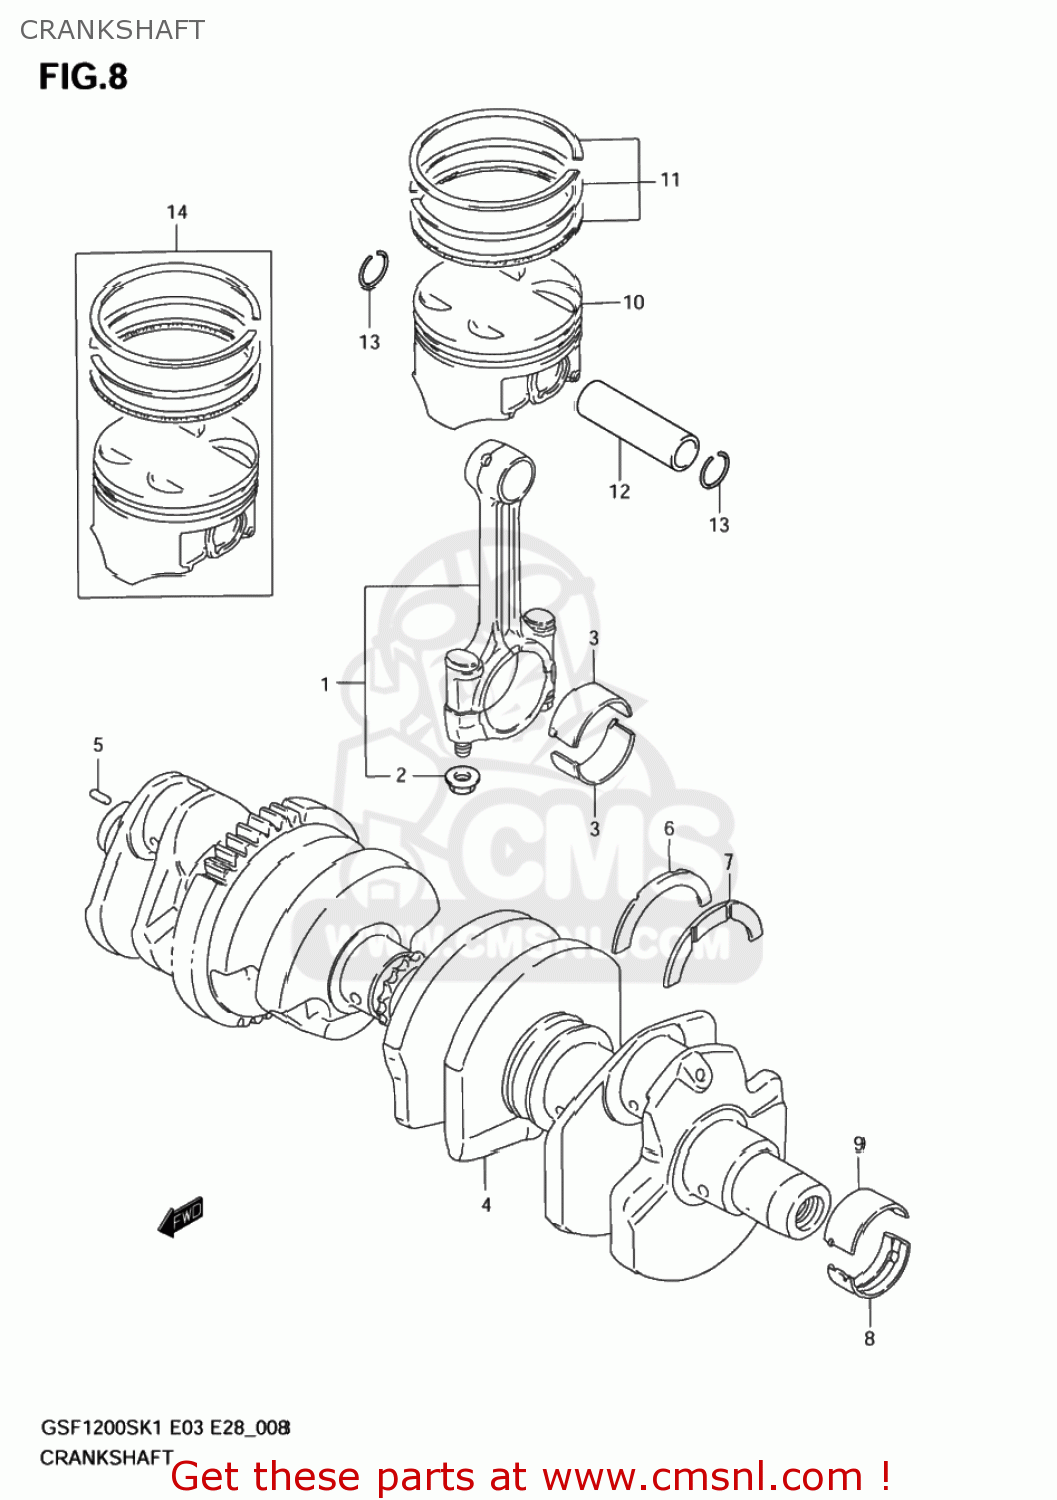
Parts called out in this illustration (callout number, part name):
1	CONNECTING ROD ASSY
2	NUT
3	BEARING,CRANK PIN
4	CRANKSHAFT SET
5	PIN
6	BEARING,CRANK THRUST(GREEN)
7	BEARING,CRANK THRUST(RED)
8	BEARING,CRANKSHAFT LWR
9	BEARING,CRANKSHAFT UPR
10	PISTON
11	RING SET,PISTON
12	PIN,PISTON
13	CIRCLIP,PISTON PIN
14	PISTON SET(OS:0.5)
